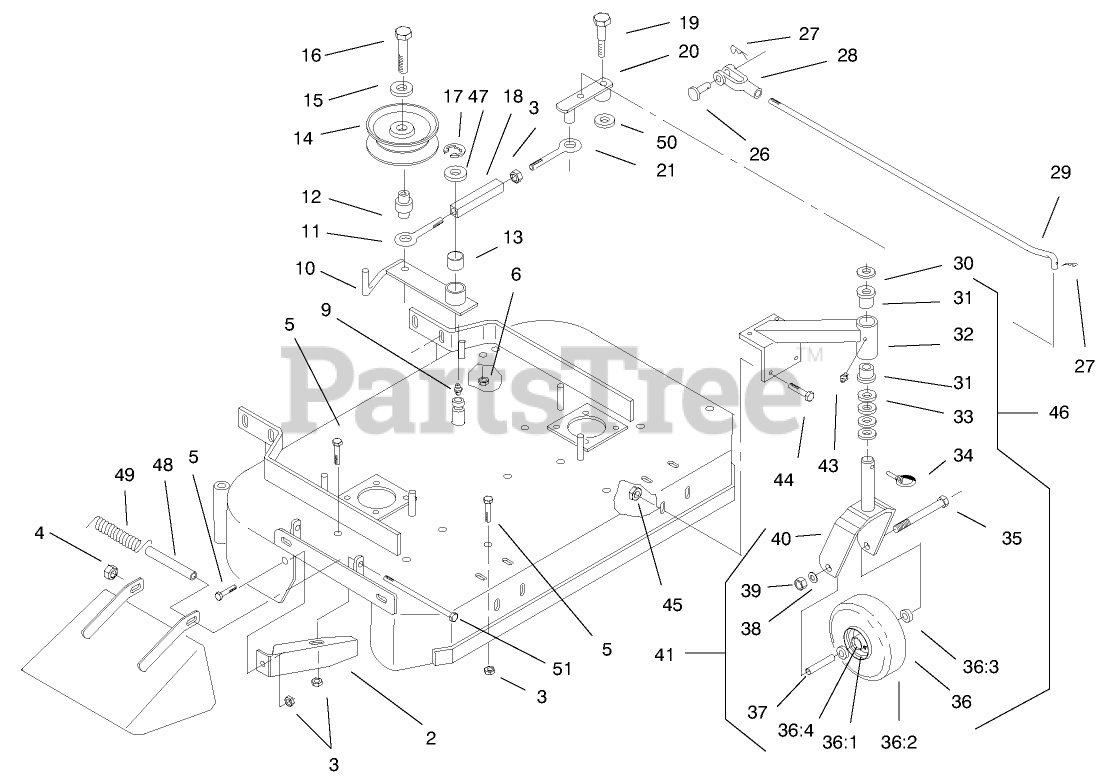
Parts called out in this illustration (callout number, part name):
2	Baffle
3	NUT-HF
4	NUT-LOCK, NI
5	Screw-HH
6	NUT-HF
9	FITTING-STRAIGHT
10	Engagement Arm w/Bushing
11	Eye Bolt
12	Bushing
13	Bearing
14	Pulley-Idler
15	WASHER-FLAT
16	Bolt-Whizlock
17	Ring-Snap
18	Turnbuckle Body
19	Bolt-Shoulder
20	Assist Arm ASM
21	Eye Bolt
26	Pin-Clevis
27	PIN-COTTER
28	Yoke
29	Linkage-Assist Arm
30	Washer
31	Bearing-Flanged
32	Support-Caster
33	Spacer
34	Pin
35	SCREW-HH
36	Tire/Wheel ASM
36:1	Wheel Hub ASM
36:2	Tire
36:3	Bearing
36:4	Bushing
37	Spacer
38	WASHER-LOCK
39	NUT-HH
40	Fork
41	Caster Wheel ASM (Incl. Ref. 36-40)
43	Zerk
44	SCREW-HH
45	NUT-FLANGE
46	Caster/Mount ASM (Incl. Ref. 31-40)
47	Spindle Washer
48	Spacer
49	Spring-Deflector
50	WASHER-THRUST
51	Screw-HH
